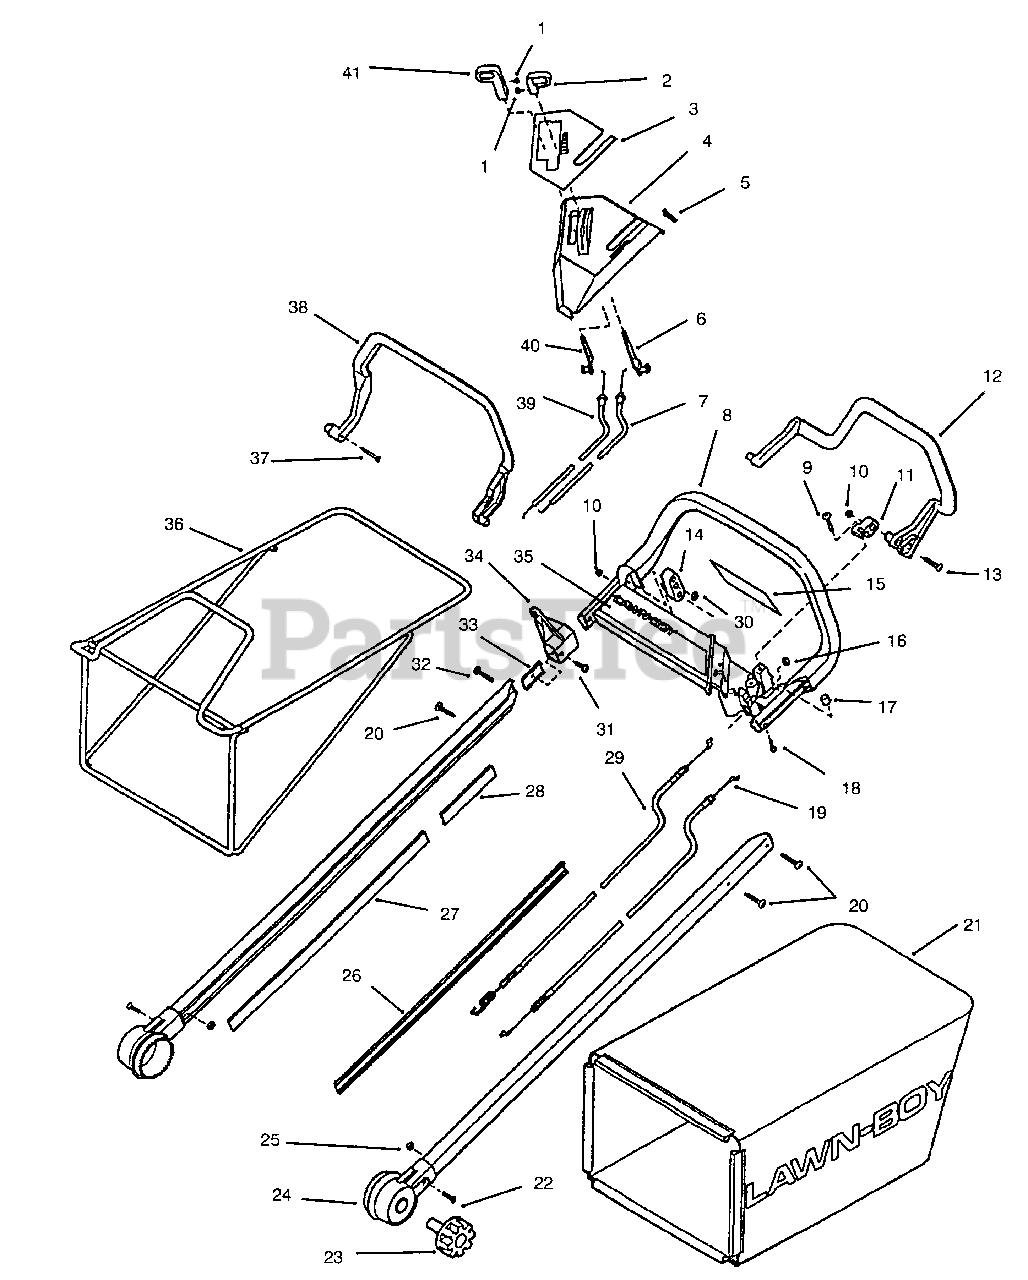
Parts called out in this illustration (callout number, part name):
1	Screw-Set
2	Assembly-Knob, Throttle (Incl. Ref. #1)
4	Assembly-Cover, Upper (Incl. Ref. #3)
6	Lever-Throttle
7	Assembly-Cable, Throttle
8	Assembly-Handle & Decal (Incl. Ref. #15, 20 & 35)
11	Pivot-Bail
12	Bail-Self-propelled
14	Block-Bail
15	Decal-Warning
16	Nut-Cable, Self-propelled
19	Assy.-Cable, Eng. Brake
20	Screw-Thread Forming
21	Bag-Rear, Grass
23	Knob-Mounting, Handle
24	Assembly-Shaft, Handle (Incl. Ref. # 23 & 25)
26	Insert-Handle, Cable Side
27	Insert-Handle
28	Insert-Handle
29	Assy.-Cable, Self-propelled
33	Plate-Nut
34	Guide-Rope
35	Decal-Lawn-Boy
38	Bail-Brake, Engine
39	Assy.-Cable,Gear Select
40	Lever-Gear, Select
41	Assy.-Knob, Gear Select (Incl. Ref. #1)
